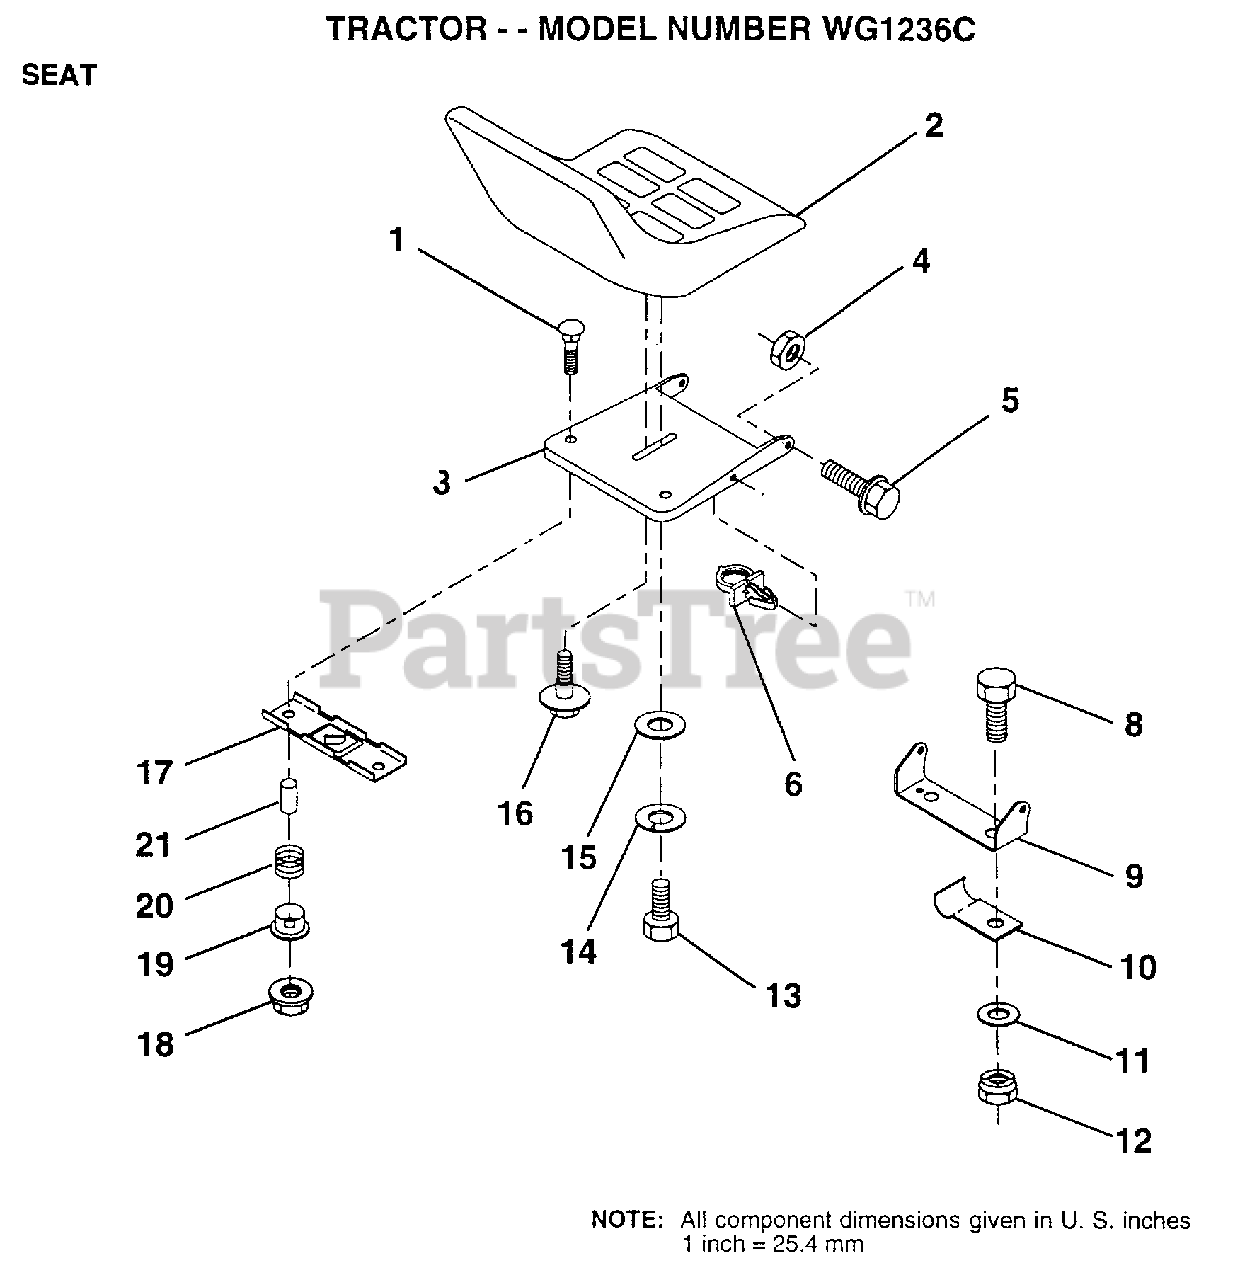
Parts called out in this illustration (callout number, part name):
4	NUT
5	BOLT.SHLD.5/16-18
6	CLIP.PUSH-IN.HING
8	BOLT
9	BRACKET PVT SEAT
10	"CLIP,INSULATOR"
11	WASHER
12	NUT
13	BOLT
14	LOCKWASHER
15	WASHER
16	"BOLT,SHOULDER"
17	BRKT SWITCH
19	BUSHING
20	SPRING
21	SPLIT SPACER
